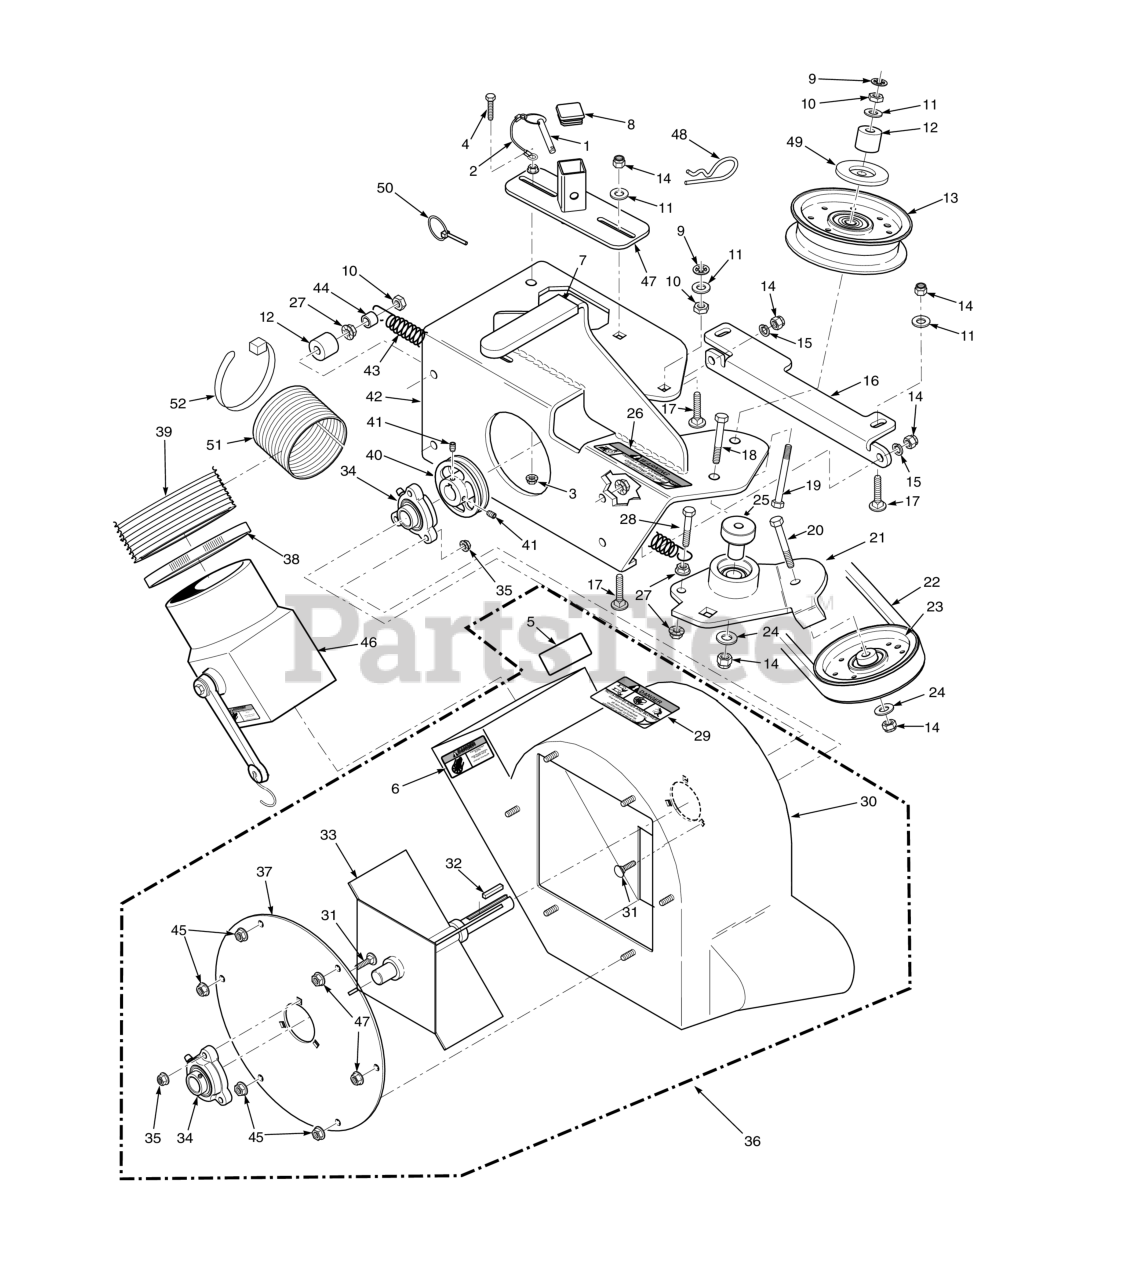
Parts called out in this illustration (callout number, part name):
1	Pin, Ring 1/2 x 2-1/4"
2	Lanyard, Deck Height Pin
3	NUT, 1/4-20 SERRATED FLANGE HEX HEAD
4	NUT, 1/4-20 SERRATED FLANGE HEX HEAD
5	Decal, Blower
6	Decal, Rotating Blower
7	Grip, Deck Latch Lever
8	Cap, Square Vinyl
9	Nut, Push-On - 3/8" Dia.
10	Bolt, Hex Head 3/8-16 x 1" Ser. Flg.
11	Flatwasher, 3/8" Special (.391 x .938 x .105)
12	SPACER, J-PULL ROD
13	Pulley, Idler 4" Dia. - 61" & 72"
14	HEX NUT, ELASTIC STOP LOCK, 3/8-16
15	Lockwasher, 3/8" Spring, Kawasaki FX / FT & FT-EFI / B&S 32BV
16	Plate, Catcher Mounting
17	Bolt, RDHD Carr. 3/8-16 x 1-1/2 (52" & 61")
18	Bolt, Hex Head 3/8-16 x 3" - 52"
19	Bolt, Hex Head 3/8-16 x 3-1/2" Full Thread
20	Bolt, Hex Head 3/8-16 x 1-3/4" (Kohler EFI)
21	Idler Arm Assembly, GC-STT 61"
22	Belt, GC-STWC 61"
23	Pulley, 3-1/2" O.D., GC-STT 52"
24	Flatwasher, 3/8 (.391 x .938 x .105 HD) Grade 8
25	Pivot, Idler - Short
26	Decal, Warning - Belt Cover
27	NUT, 3/8-16 SERRATED FLANGE HEX HEAD
28	Bolt, Hex Head 3/8-16 x 1-1/2" Grade 8 Black
29	Decal, Danger
30	Blower Housing Weldment w/Decals
31	Bolt, 5/16-18 x .75 RHSN Carriage
32	KEY 1/4 X 1/4 X 1 1/2"(FOR 1" CRANKSHAFT
33	Fan Weldment
34	Bearing Assembly
35	HEX NUT, ELASTIC STOP LOCK, 5/16-18
36	Blower Housing Assembly, GC-STT
37	COVER, BLOWER HOUSING
38	Clamp, 8-5/8" Max Dia. (61")
39	Hose, 8.00" Dia. x 53" Long
40	Pulley, 4-3/4" O.D. - 1" Bore
41	Setscrew, Hex Socket Knurl Cup Pt. 5/16 - 18 (nylock)
42	Frame, Blower Mount
43	Spring, Helper (61" Cutter Deck Only)
44	Spacer, Deck Assist
45	Nut, Serrated Flange 5/16-18 (Right Front Engine Mounting, Briggs and Kohler Only)
46	Adapter, Blower GC-STC,
47	Receiver Weldment, Mount Post - 61"
48	Hair Pin Cotter, .177" x 3-1/4"
49	Quick Pin, 5/16" Dia.
50	Quick Pin, 5/16" Dia.
51	Hose, 8" Dia. x 24" Split
52	Cable Tie, .345 X 31.5 Black
